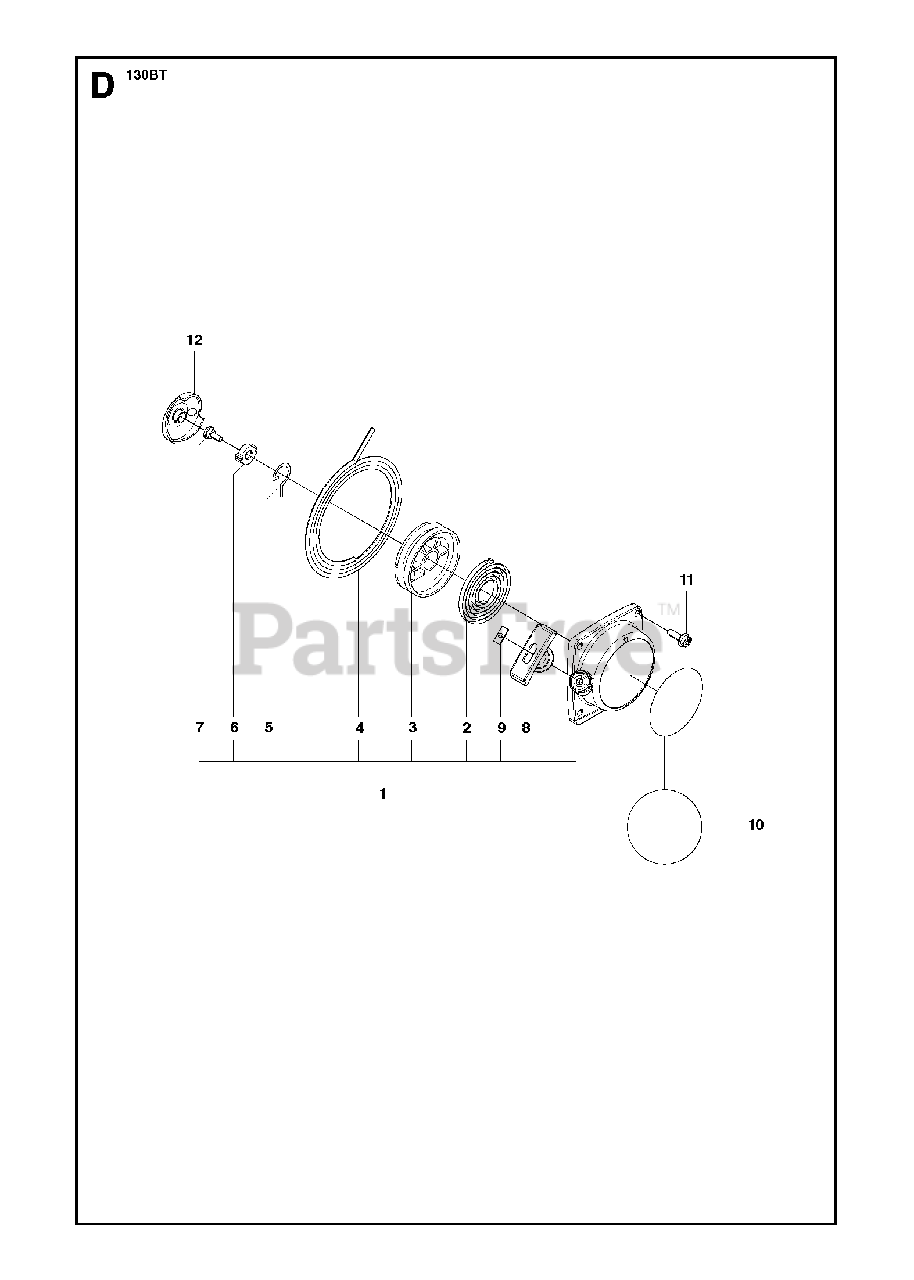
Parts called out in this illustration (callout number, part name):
2	SPRING, SPIRAL
3	REEL
4	ROPE
5	SWING ARM
6	COLLAR
7	SCREW
8	KNOB
9	KNOB
10	LABEL RECOIL
